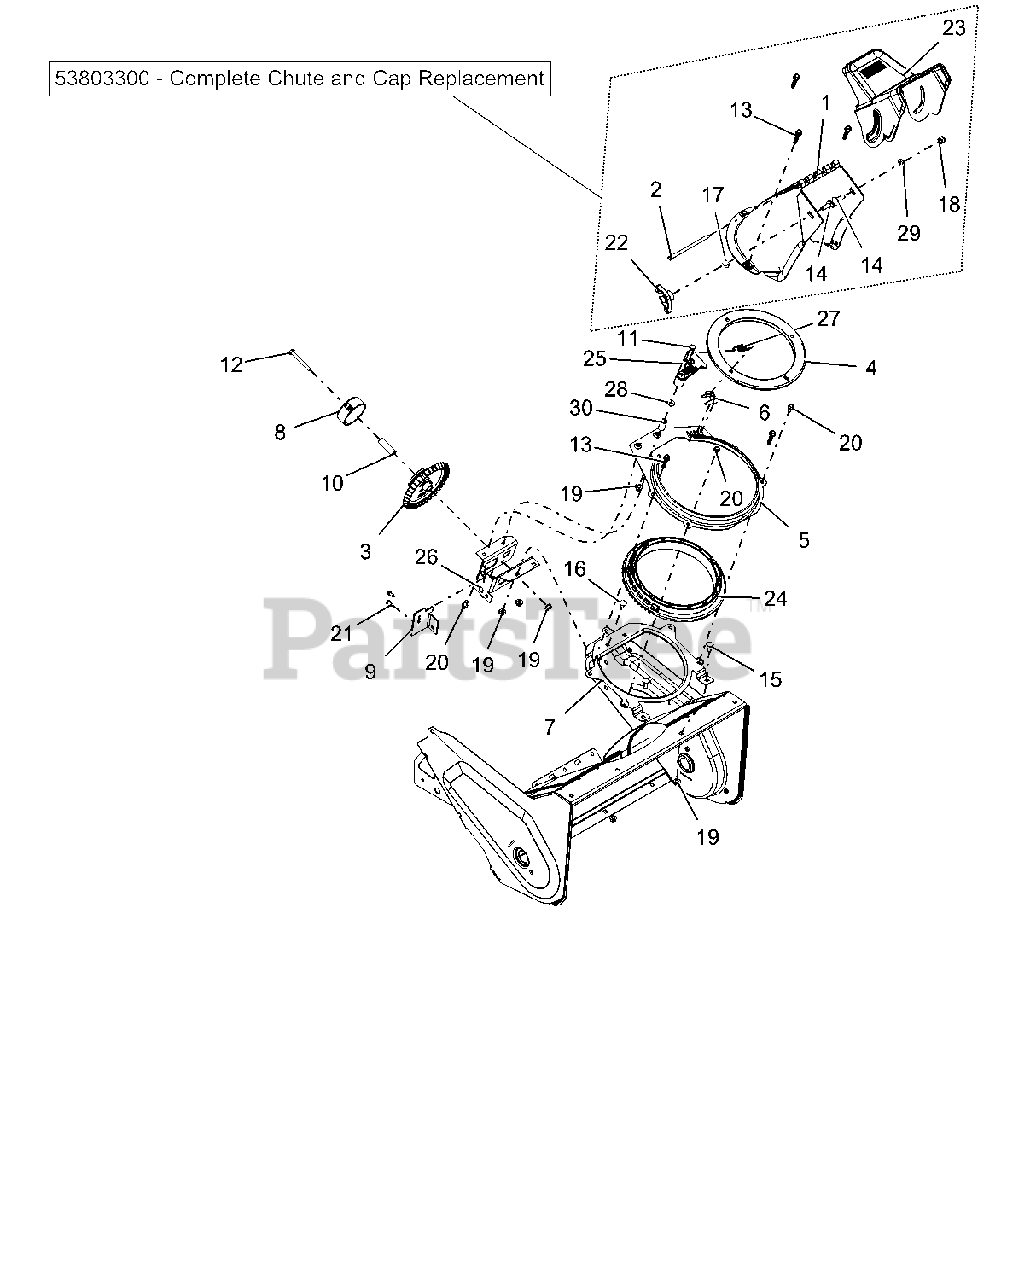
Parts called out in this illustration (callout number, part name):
1	CHUTE, SINGLE STAGE
2	ROD, CONNECTING, 1/4 X 4-1/2
3	GEAR, CHUTE
4	GUARD, WATER
5	RING, CHUTE MOUNT - UPPER
6	BRKT, SPRG
7	RING, CHUTE MOUNT - LOWER
8	COVER, CHUTE SPOOL
9	BRKT, CABLE ANCHOR
10	BSHG, SLV .265X.505X1.665
11	@BLT-HEX .25-20X1.50 GR5 YWZC
12	@BLT-HEX .25-20X2.25 GR5 YWZC
13	SCR-TAP .25-10X1.25 HWH YWZC
14	BLT,RNHDRECSHNK .31-18X1.00
15	@BLT-RDHDSQNK .25-20X.75 G5YZ
16	@BLT-RDHDSQNK .25-20X.50 G5YZ
17	@WSHR-FL-STL.344X.688X.065YWZC
18	@NUT-LK-NYL .312-18 YWZC
19	@NUT-LK-TOP-FLG .25-20 YWZC
20	SCR-TAP .25-20X.50 HWH TR YWZ
21	@SCR-TAP 10-24X.50 HWH TR YWZC
22	KNOB,WING .31-18 UNC NYL/TALC
23	KIT, CAP REPLACEMENT
24	GEAR, CHUTE RING
25	KIT, PAWL ARM REPLACEMENT
26	BRKT, BEVEL GEAR
27	SPRG, TENSION .052X.520X1.74
28	@WSHR-FL-STL.281X.62X.065 YWZC
29	@WSHR-FL-STL.344X.688X.065YWZC
30	BSHG, SLV .265X.505X.995
31	KIT, CHUTE AND CAP REPLACEMENT
